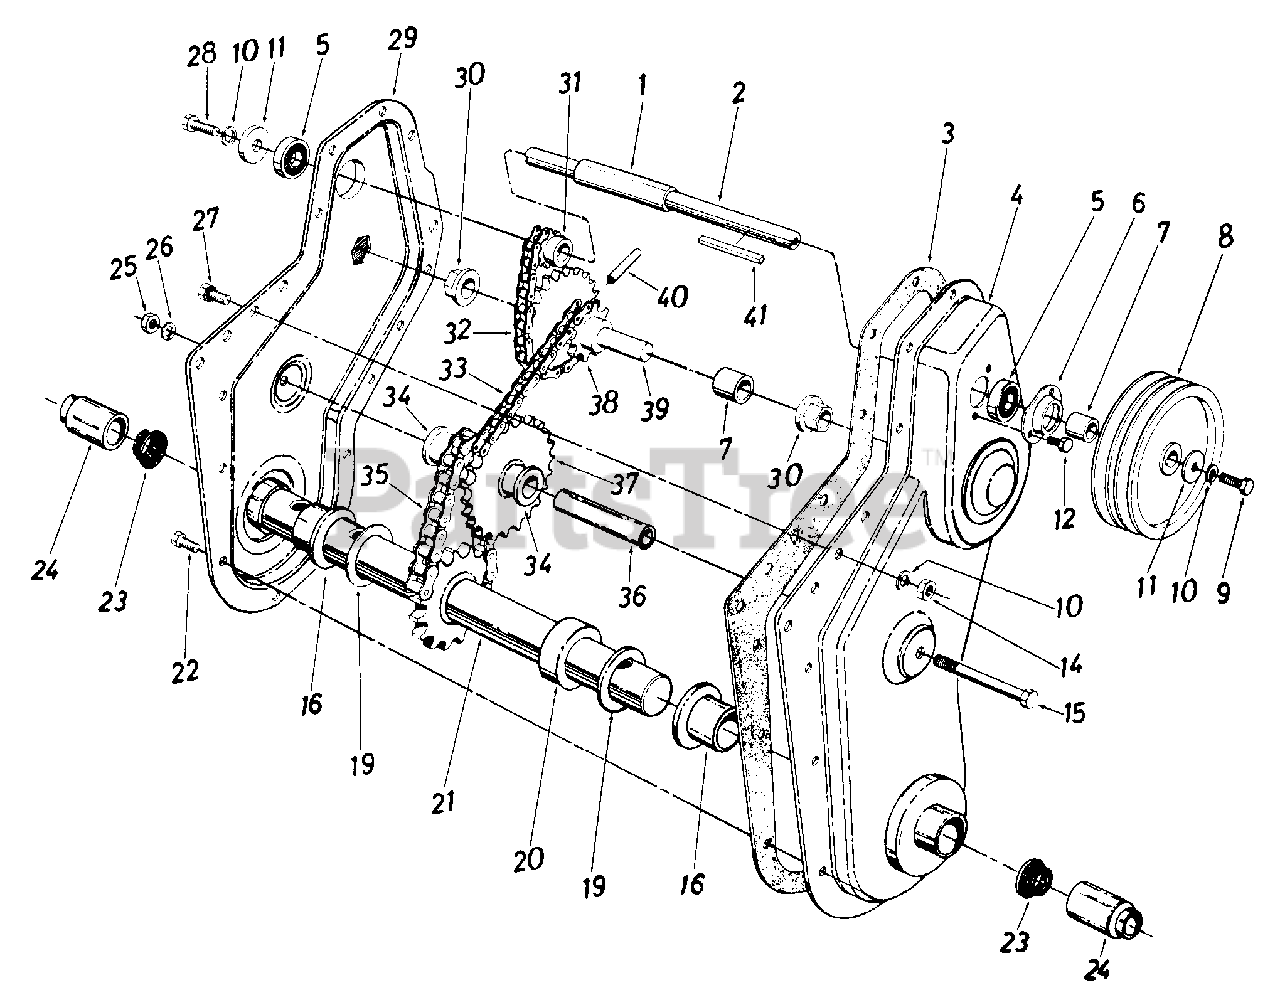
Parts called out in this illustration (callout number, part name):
2	SHAFT-JACK
3	GASKET
4	CHAIN CASE HALF-LH
5	BEARING-BALL
6	HOUSING-BRG
7	SPACER-.635 ID X .88 OD X 1.03
9	SCREW-HEX 5/16-18 X 10 SPEC
10	WASHER-LOCK-5/16
11	WASHER-FL-.312 X 1.125 X .125
12	SCREW-HEX WASH SF TAPP
14	NUT-HEX 5/16-18
15	SCREW-HEX 3/8-16 X 3.25
16	BEARING-KING PIN
19	WASHER-FL-1.03 ID X 1.62 X .03 HD
21	SHAFT-TINE
22	SCREW-HEX WASH SF TAPP
24	CAP-DUST
25	NUT-HEX 3/8-16
26	WASHER-LOCK-3/8
27	SCREW-HEX SEMS 5/16-18 X 1.00
28	SCREW-HEX 5/16-18 X .62
29	CHAIN CASE HALF-RH
30	BEARING-HEX FLANGE
31	SPROCKET ASSY-10T
32	#41 CHAIN 1/2 PITCH X 34 LINKS E
33	#420 CHAIN 1/2 PITCH X 48 LINKS
34	BEARING-FLANGE .626 ID
35	#50 CHAIN 5/8 PITCH X 28 LINKS
36	SHAFT-SPROCKET
37	SLEEVE ASSY-SPRKT
38	SLEEVE ASSY-SPRKT
39	SHAFT-SPROCKET
40	PIN-SPRING SPIRAL 1/4X1.5 HEAVY DT
41	KEY-SQ 3/16X1.50
